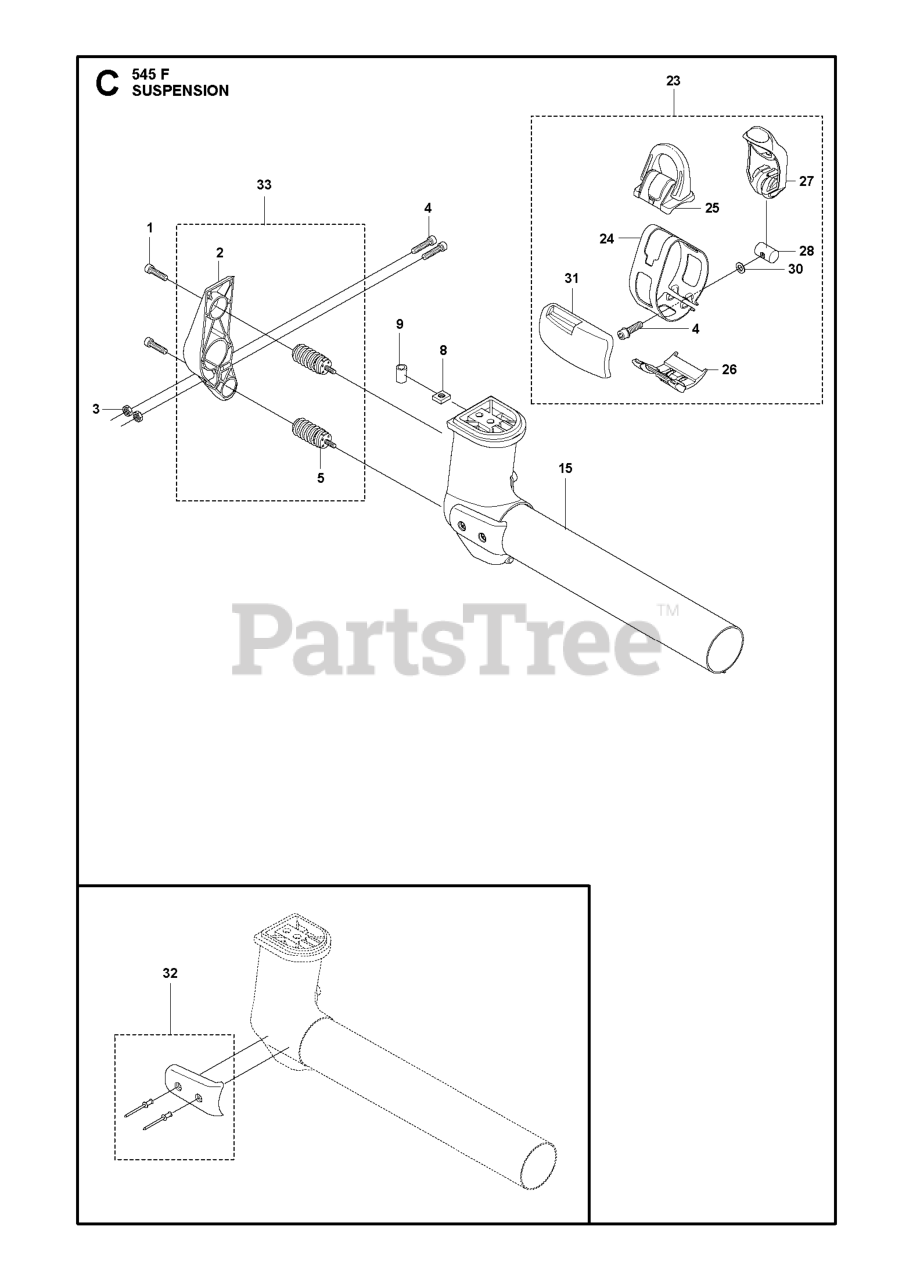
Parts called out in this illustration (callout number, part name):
2	HOLDER ANTIVIBRATION
5	ANTIVIBRATION ELEMENT ASSY
15	SUSPENSION
26	GUIDE RAIL
30	WASHER 5.3X12
31	WEAR PROTECTION
32	WEAR PROTECTION KIT
